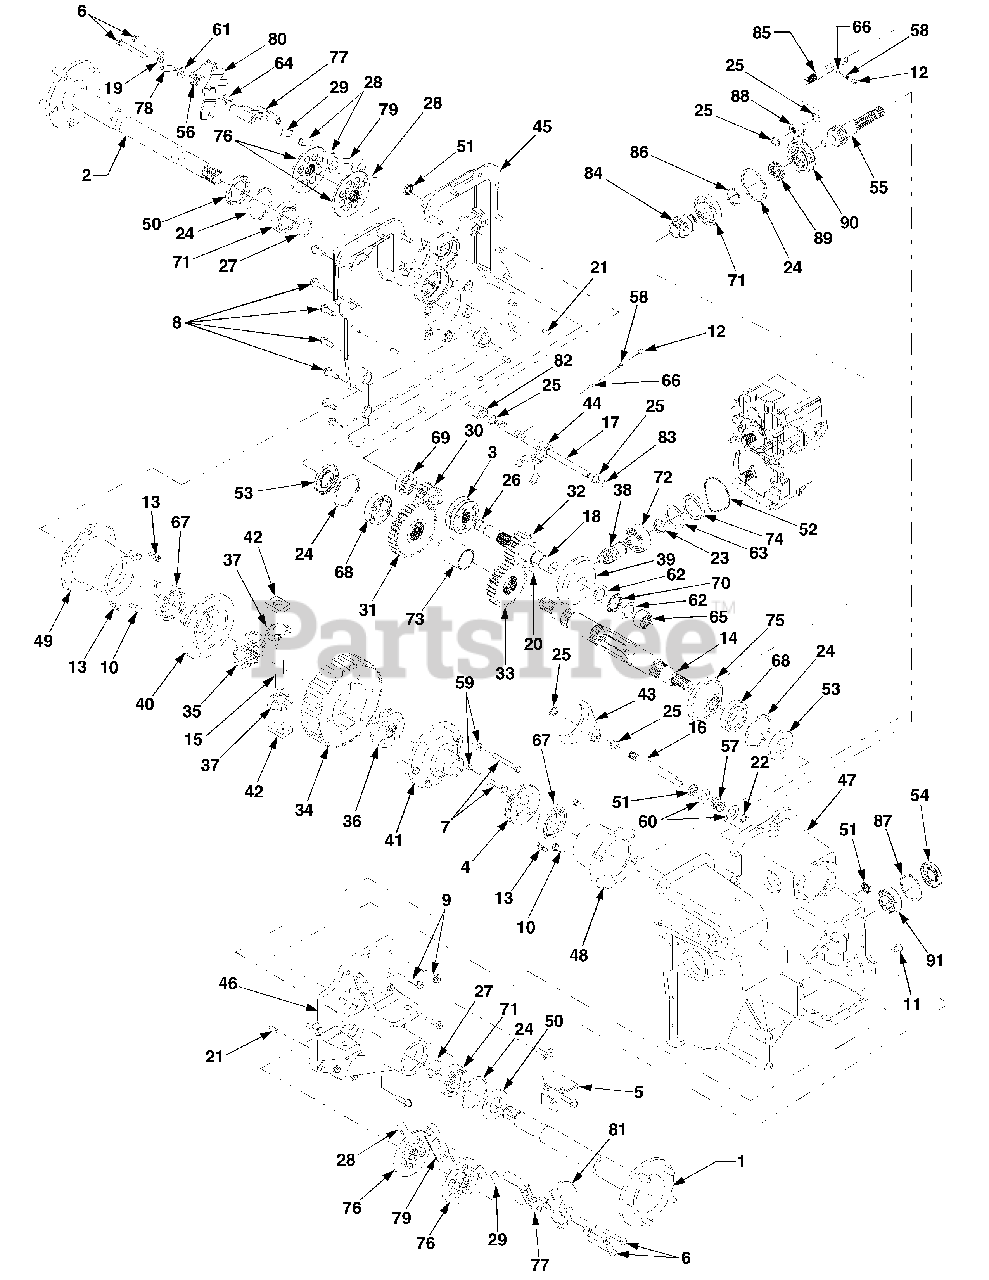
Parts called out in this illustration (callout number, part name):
1	Shaft, Axle RH
2	Shaft, Axle LH
3	Collar Assembly, Hi-Lo
4	Collar Assembly, Diff Lock
5	Bracket, Diff. Lock
6	Screw, Hex Cap, 5/16-18 x 2.75 GR5
7	Screw, Hex Cap, 5/16-18 x 2.5 GR5
8	Screw, Hex Wash. Hd. Tapp, 5/16-18 x 1.0
9	Screw, Hex Wash. Hd. Tapp, 5/16-18 x 1.25
10	Screw, Hex Cap, w/Patch 5/16-18 x .75GR5
11	Screw, Plug, M14 x 1.5 x .827
12	Screw, Set, 5/16-18 x .375
13	Screw, Shoulder .309 x .375: 1/4-20
14	Shaft, Output, 11T
15	Shaft, Cross, .625 x 3.95
16	Shaft, Diff. Lock Actuator
17	Shaft, Hi-Lo Actuator
18	Shaft, Drive
19	Nut, Hex Insert Lock, 5/16-24
20	Key, Woodruff, 1/4 x 3/4
21	Pin, Dowel, .25 x .75
22	Ring, Retaining
23	Ring, Snap
24	Ring, Retaining
25	Clip, Rotor
26	Ring, Retaining
27	Ring, Retaining
28	Pad, Brake
29	Plate, Brake Puck
30	Gear, Spur, 12T
31	Gear, Spur, 34T
32	Gear, Spur, 19T
33	Gear, Spur, 27T
34	Gear, Spur, 56T
35	Gear, Bevel, 16T
36	Gear, Bevel, 16T Lock
37	Gear, Bevel, 10T Diff.
38	Gear, Spiral Bevel, 13T
39	Gear, Spiral Bevel, 54T
40	Cover, Differential
41	Cover, Differential Lock
42	Block, Thrust
43	Yoke, Diff. Lock Actuator
44	Yoke, Shift, Hi-Lo
45	Cover, Trans. Large
46	Cover, Trans. Small
47	Housing, Trans.
48	Housing, Axle Inner - RH
49	Housing, Axle Inner - LH
50	Seal, Oil
51	Seal, Oil
52	Seal, Gland
53	Seal, Oil
54	Seal, Oil
55	Shaft, 4WD
56	Spring, Torsion
57	Spring, Compression, .845 x 1.0
58	Spring, Compression, .24 x .563
59	Washer, Lock, 5/16
60	Washer, Flat, .597 x 1.0 x .04 ..
61	Washer, Flat, .343 x .88 x .062
62	Washer, Thrust
63	Washer, Flat, 1.52 x 2.0 x .030
64	Pin, Brake Actuating
65	Bearing, Needle
66	Ball, Detent
67	Bearing, Ball
68	Bearing, Ball
69	Bearing, Ball
70	Bearing, Needle Thrust
71	Bearing, Ball
72	Bearing, Ball
73	Spacer, 1.51 x 1.75 x 2.41
74	Spacer, 1.515 x 2.039 x .335 ...
75	Gear, Spiral Bevel, 36T
76	Disc, Brake
77	Yoke, Brake
78	Bracket, Brake Anti Rotation
79	Plate, Puck Retainer
80	Arm, Brake Actuator - LH
81	Arm, Brake Actuator - RH
82	Spacer, .573 x .938 x .832
83	Plug, .437 x .16
84	Gear Assembly w/Bearings
85	Shaft, 4WD Actuator
86	Ring, Retaining
87	Ring, Retaining
88	Yoke, 4WD
89	Gear, Spline Coupling
90	Collar, Shift
91	Bearing, Ball
